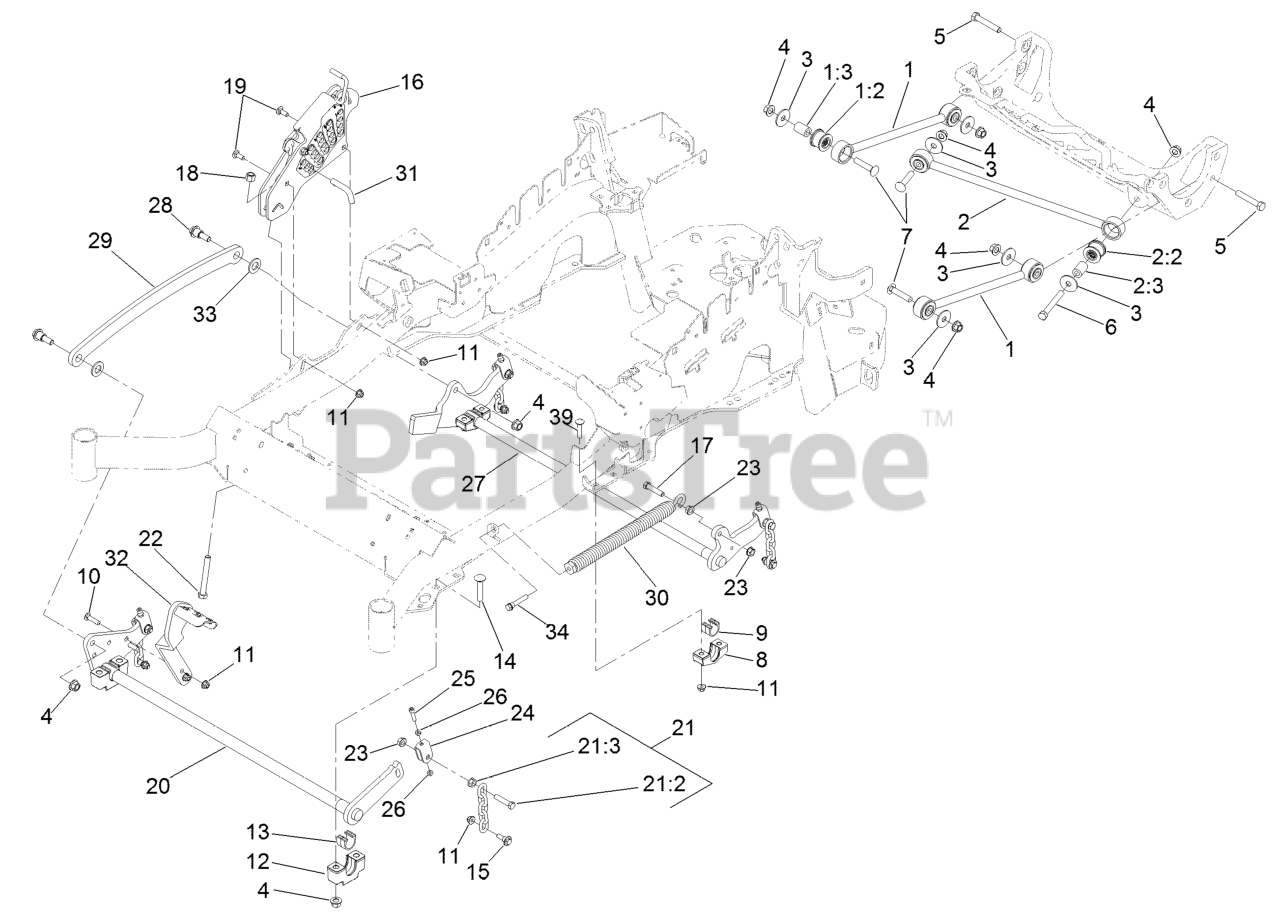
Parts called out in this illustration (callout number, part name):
1	DECK STRUT ASM
1:2	BUSHING-SUSPENSION, RUBBER
2	PANHARD ROD ASM
2:2	BUSHING-SUSPENSION, RUBBER
3	WASHER-THRUST
4	Nut-Lock 1/2-13
5	SCREW-HH
6	SCREW-HH
7	SCREW-CARR
9	BEARING-CROSS SHAFT, REAR
10	SCREW-CARR
11	NUT-HF, NI
12	SUPPORT-CROSS SHAFT, BEARING
13	BEARING-CROSS SHAFT, FRON
14	Bolt-Carriage 1/2-13 X 2 1/2 Spl Neck
15	SCREW-SHOULDER, HHF
16	HOC ASM
17	SCREW-HH
18	NUT-LOCK, NI
19	BOLT-CARR
21	DECK LIFT CHAIN ASM
21:2	SCREW-HH
22	BOLT-TAP
24	YOKE-ADJUST, DECK
25	SCREW-HSH
26	NUT-JAM
27	LIFT-DECK, REAR
28	SCREW-SHOULDER, HHF 1/2-13 X 1.12
29	LINK-LIFT, DECK
30	SPRING-EXTENSION
31	PIN-HOC
32	LEVER-FOOT
33	WASHER-FLAT
34	BOLT-SHOULDER
39	SCREW-CARR
